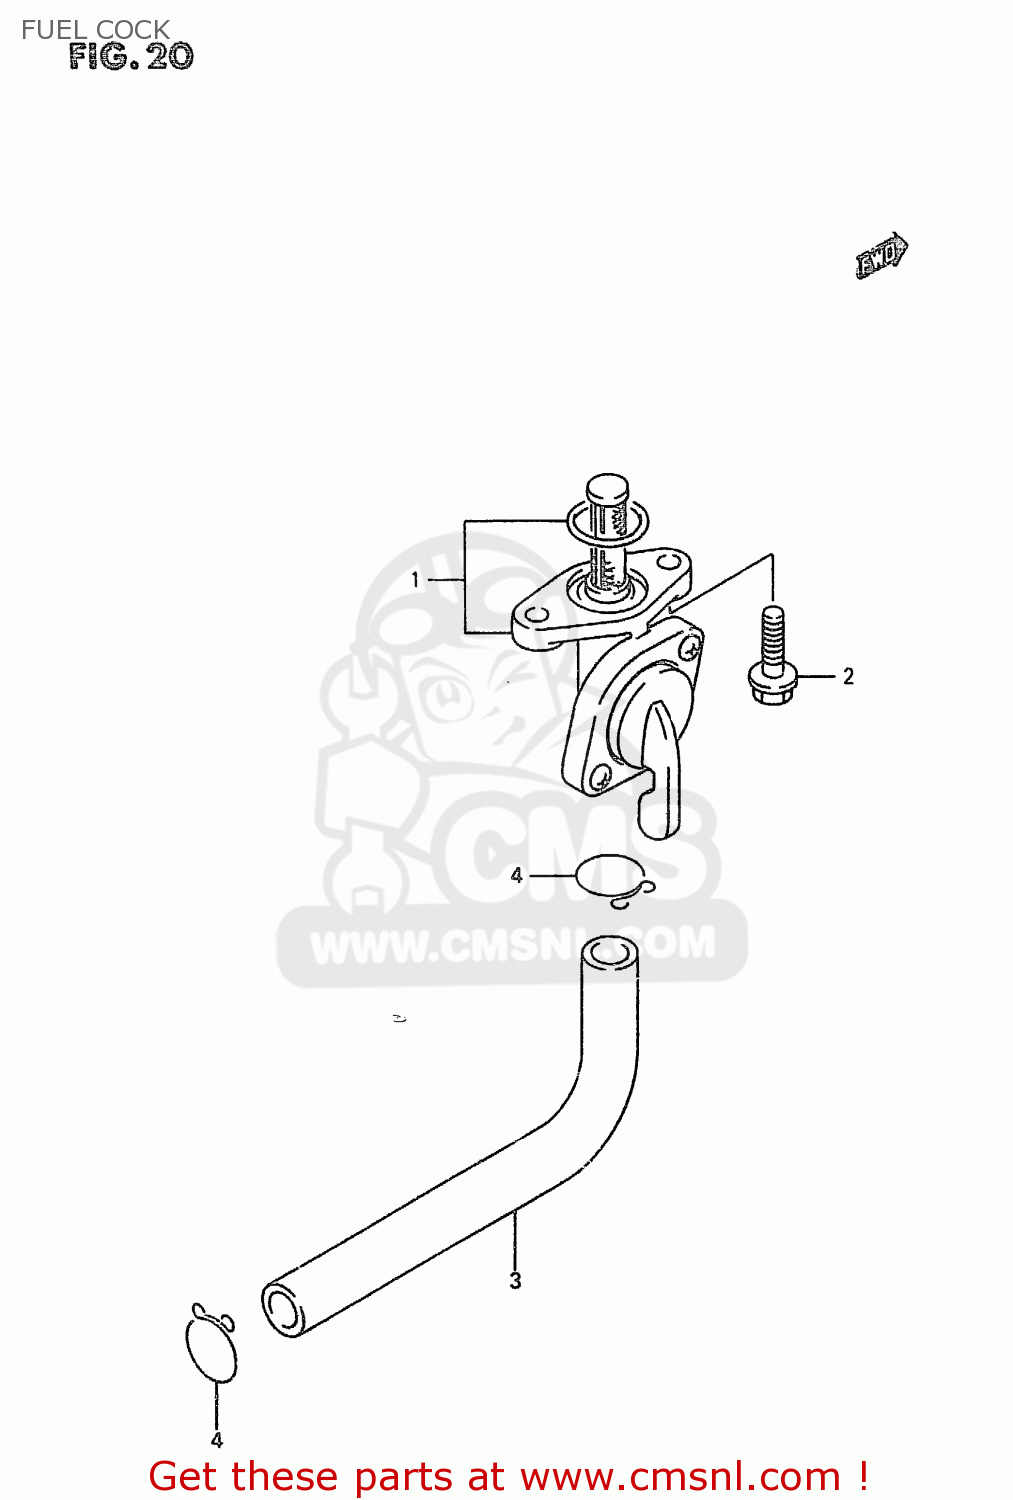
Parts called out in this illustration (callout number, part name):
1	COCK ASSY,FUEL
2	BOLT
3	HOSE,FUEL
4	CLIP
